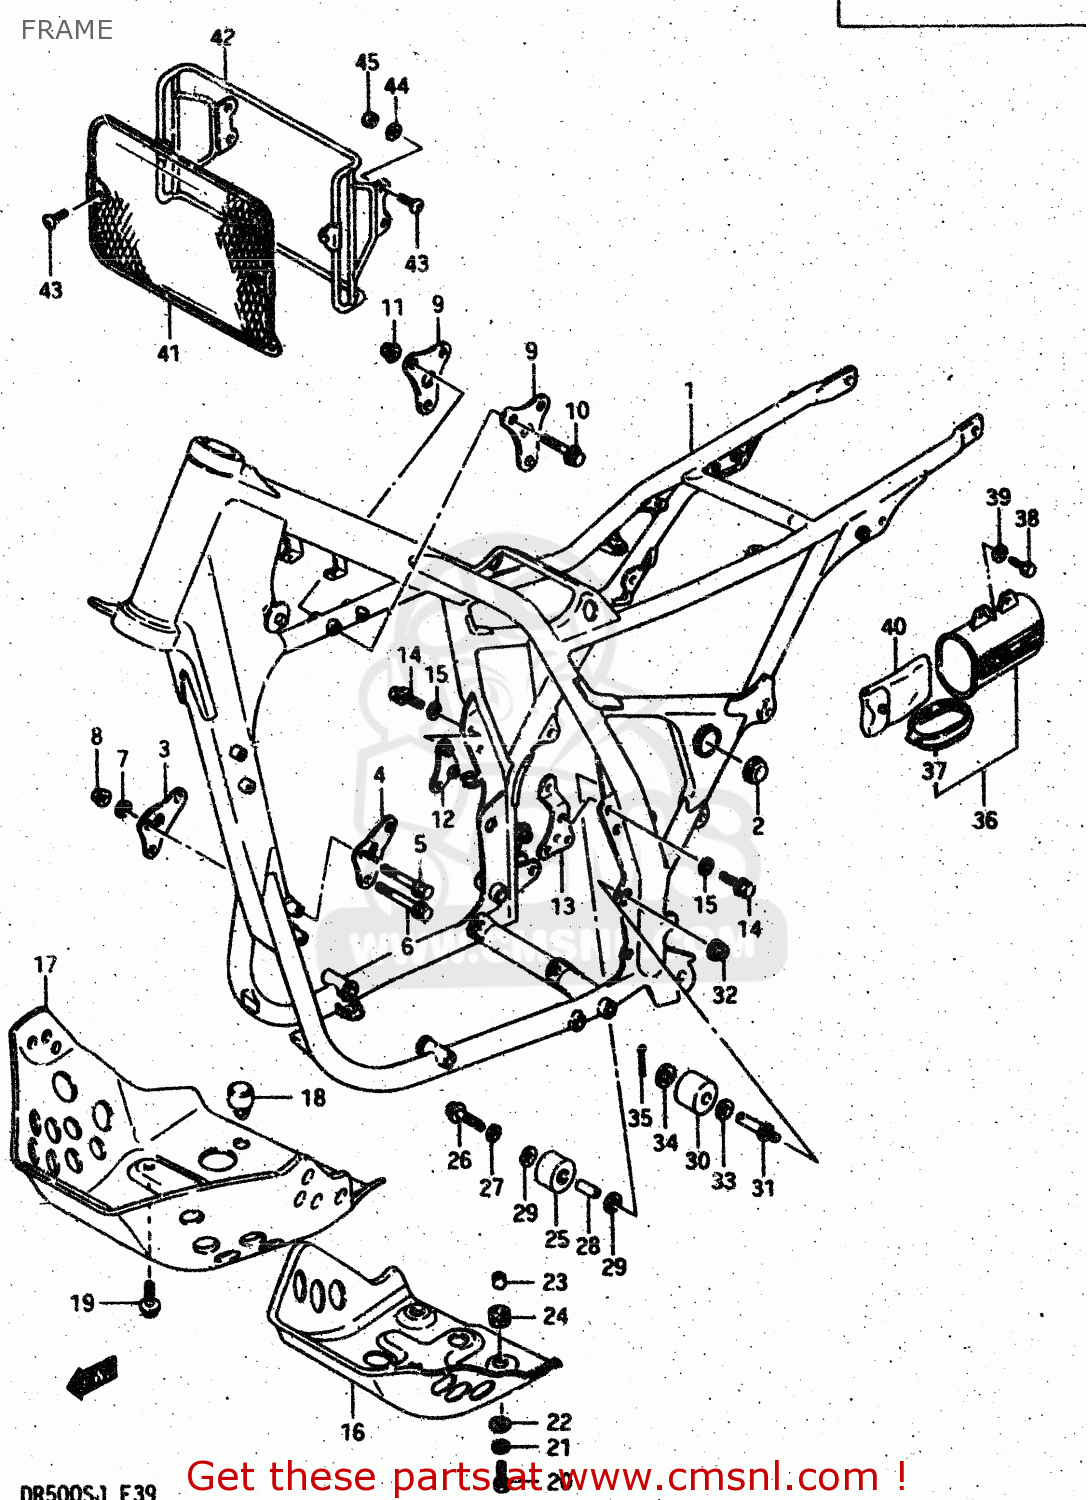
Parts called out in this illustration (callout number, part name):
1	FRAME (BLUE)
2	CAP,CUSHION LE
3	PLATE,ENGINE MOUNTING,FRONT
4	PLATE,ENGINE MOUNTING,FRONT
5	BOLT(8X67)
6	BOLT(8X75)
7	WASHER,LOCK
8	NUT
9	PLATE,ENGINE MOUNTING,UPPER
10	BOLT
11	NUT
12	PLATE,ENGINE MOUNTING,REAR
13	PLATE,ENGINE MOUNTING,REAR
14	BOLT
15	WASHER,LOCK
16	PROTECTOR,ENGINE
17	PROTECTOR,ENGINE
18	CUSHION
19	BOLT
20	BOLT 8X16
21	WASHER,LOCK
22	WASHER
23	SPACER (7X9X7)
24	CUSHION
25	ROLLER,CHAIN CONTROL
26	BOLT 8X40
27	WASHER,LOCK
28	SPACER(8.6X12X25.5)
29	WASHER
30	ROLLER,CHAIN LENGTH CONTROL
31	BOLT,CHAIN LENGTH CONT LWR
32	NUT
33	WASHER
34	WASHER
35	PIN 25X20
36	HOLDER,TOOL
37	CAP,HOLDER
38	BOLT 6X16
39	WASHER (6.5X18X1.6)
40	TOOL ASSY
41	GUARD, HEADLAMP
42	BRACE, HEADLAMP GUARD
43	SCREW 6X12
44	WASHER
45	NUT
